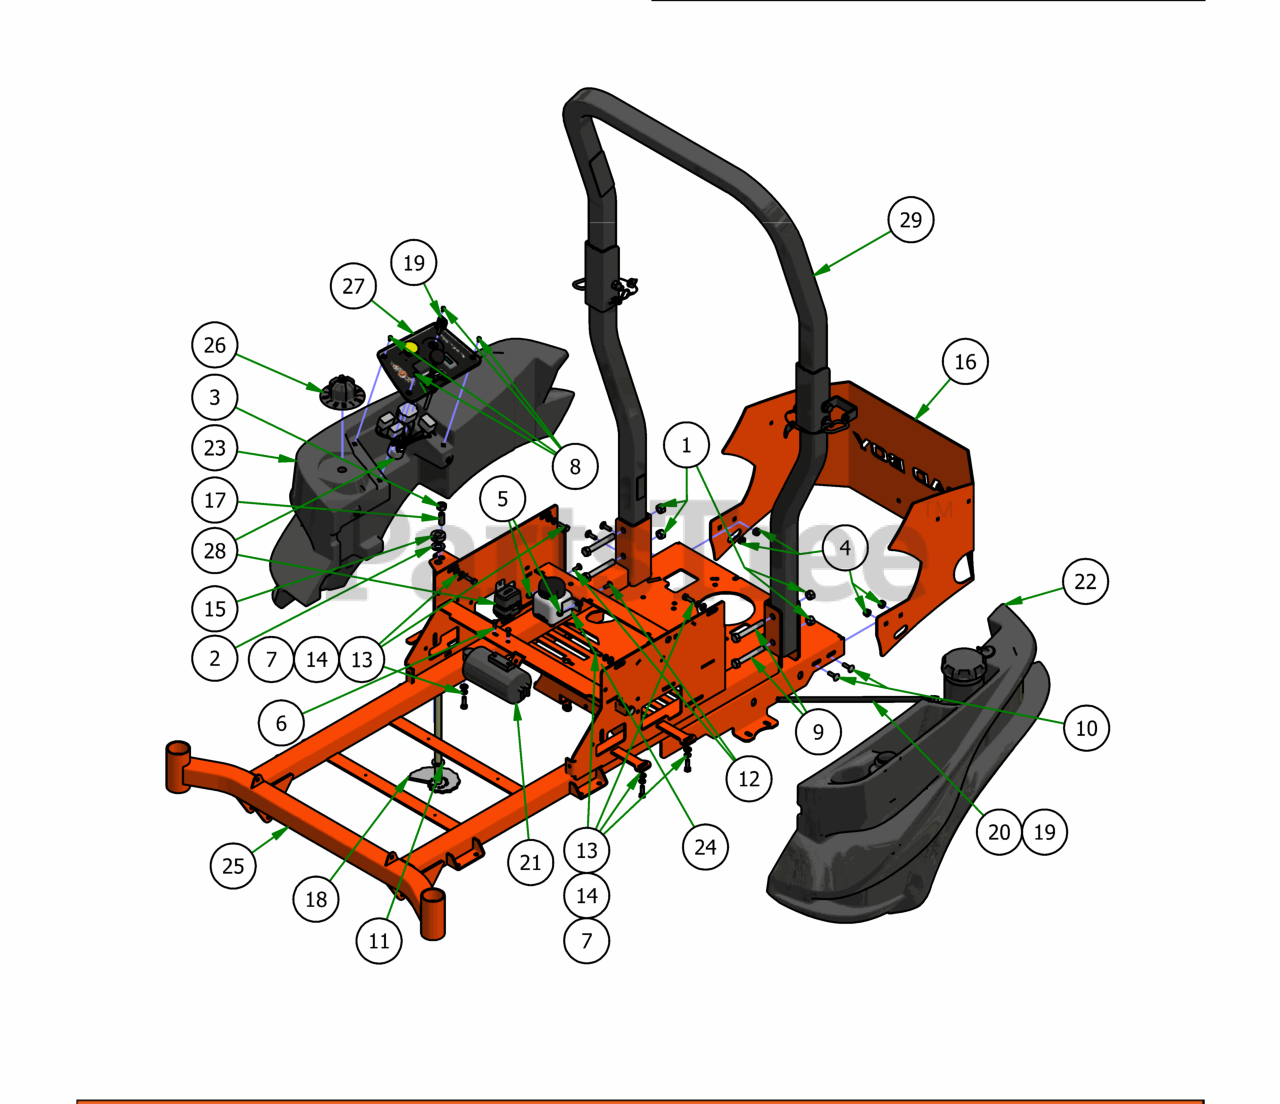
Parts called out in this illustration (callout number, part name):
1	1/2" Center Lock Nut
2	.625 ID x 1.250 OD x .062 THK F/W Nylon
3	1/2" Hex Nut
4	5/16-18 Nylon Flange Nut
5	1/4" Nylock Nut
6	M6-1.0 X 16MM Hex Bolt
7	5/16" x 1" Bolt
8	10-32 x 3/8" Button Socket Head Bolt
9	1/2-13 x 3 1/2 GR 5 Hex Bolt
10	5/16" x 1" Carriage Bolt
11	.630 ID x 1.122 OD x .142 THK Plastic Washer
12	1/4" x 3/4" Carriage Bolt
13	5/16" Flat Washer
14	5/16" Lock Washer
15	5/8" Split Collar
16	2017 ZT Rear Plate
17	Dial Rod Plunger
18	ZT Deck Height Bar Assembly
19	Ignition Key
19	Vanguard Fuel Line Assy-37"
20	2015 ZT KawaFuel Line Assy-22"
21	ZT/Mav EPA Cannister Assy
22	Left Fuel Tank
23	Right Side Console
24	Hydro Tank Assembly
25	2018 Compact Outlaw Frame
26	MZ/ZT Deck Height Dial
27	2019 ZT/Maverick Control Panel Assembly
28	Wiring Harness
29	2016 2x2 ROPS
